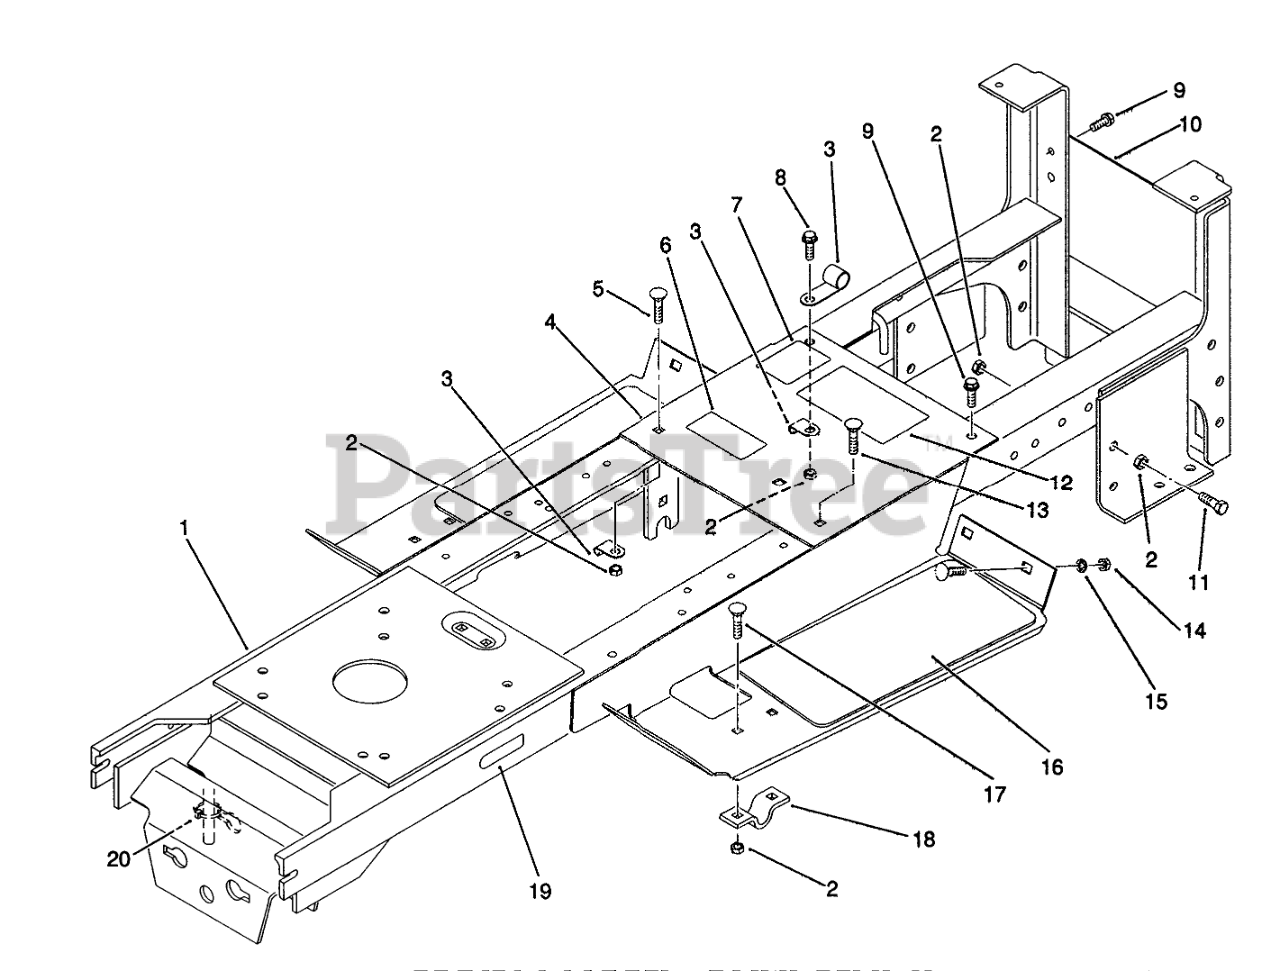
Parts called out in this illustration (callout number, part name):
1	WELDMENT-FRAME R
2	Nut
3	THROTTLE CONTROL CLP
4	Panel
5	Bolt-Carriage
6	Decal-Danger
7	DECAL-PARKING BRAKE
8	SCREW-HWHTF
9	Bolt
10	PANEL-REAR R
11	Screw-Cap. Hex. Hd.
12	DECAL-DANGER
13	Bolt-Carriage
14	Nut
15	Washer-Lock
16	PAD FOOTREST
17	Bolt-Carriage
18	CLAMP
19	Decal-Attac-O-Matic
20	PLASTIC TIE
